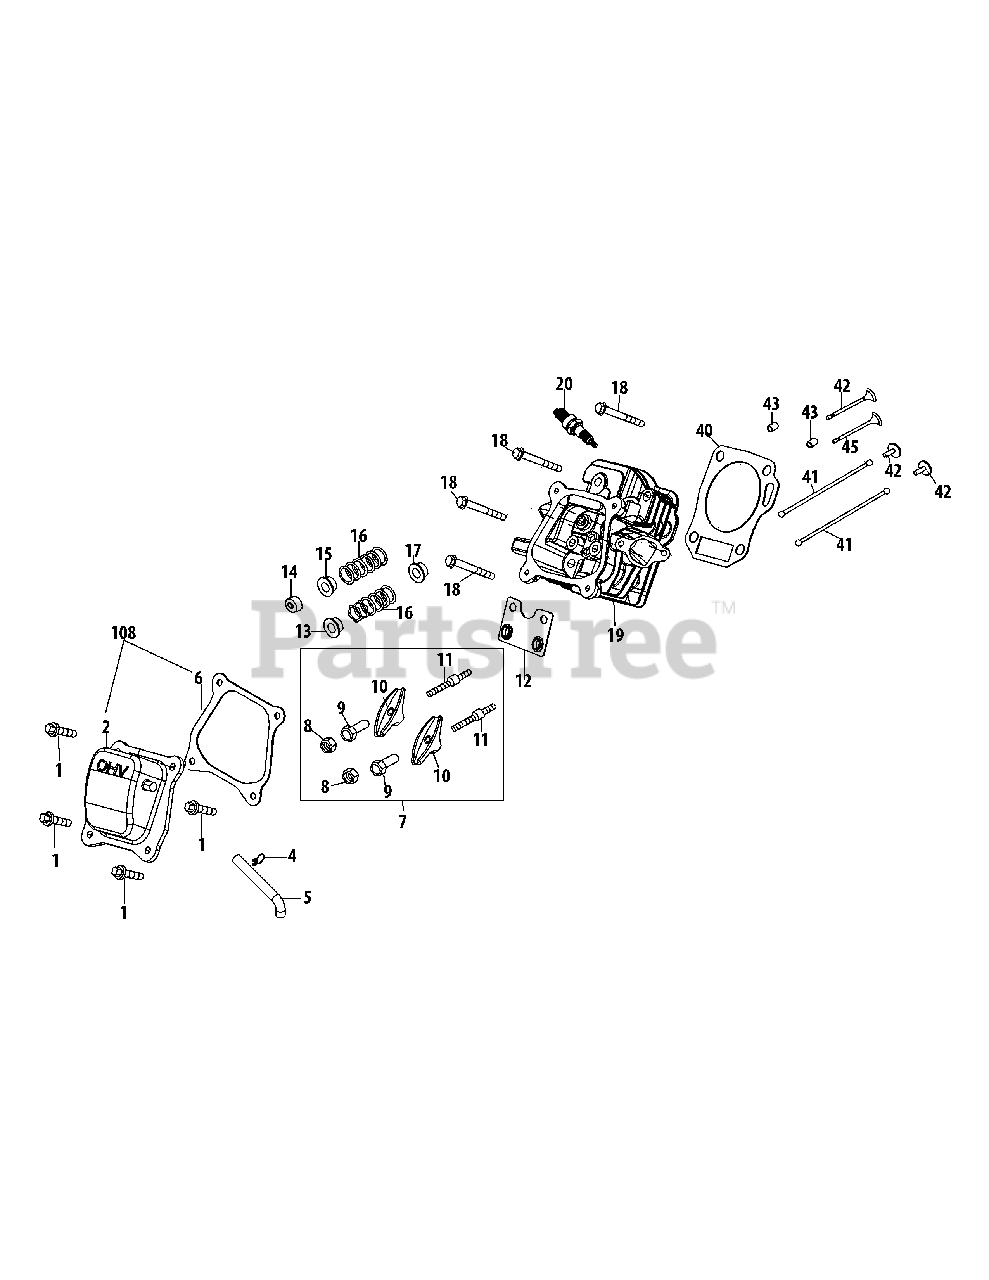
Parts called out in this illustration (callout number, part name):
1	Bolt M6×16
2	Valve Cover
4	Breather Hose Clamp
5	Breather Hose
6	Valve Cover Gasket
7	Rocker Arm Assembly
8	Nut, Pivot Locking
9	Adjusting Nut, Valve
10	Rocker Arm
11	Bolt, Pivot
12	Push Rod Guide
13	Retainer, In.Valve Spring
14	Adjuster, Ex. Valve
15	Retainer, Ex. Valve Spring
16	Valve Spring
17	Intake Valve Seal
18	Bolt M8×55
19	Cylinder Head
20	Spark Plug
40	Gasket, Cylinder Head
41	Push Rod Kit
43	Dowel Pin 10×16
108	Valve Cover Kit
